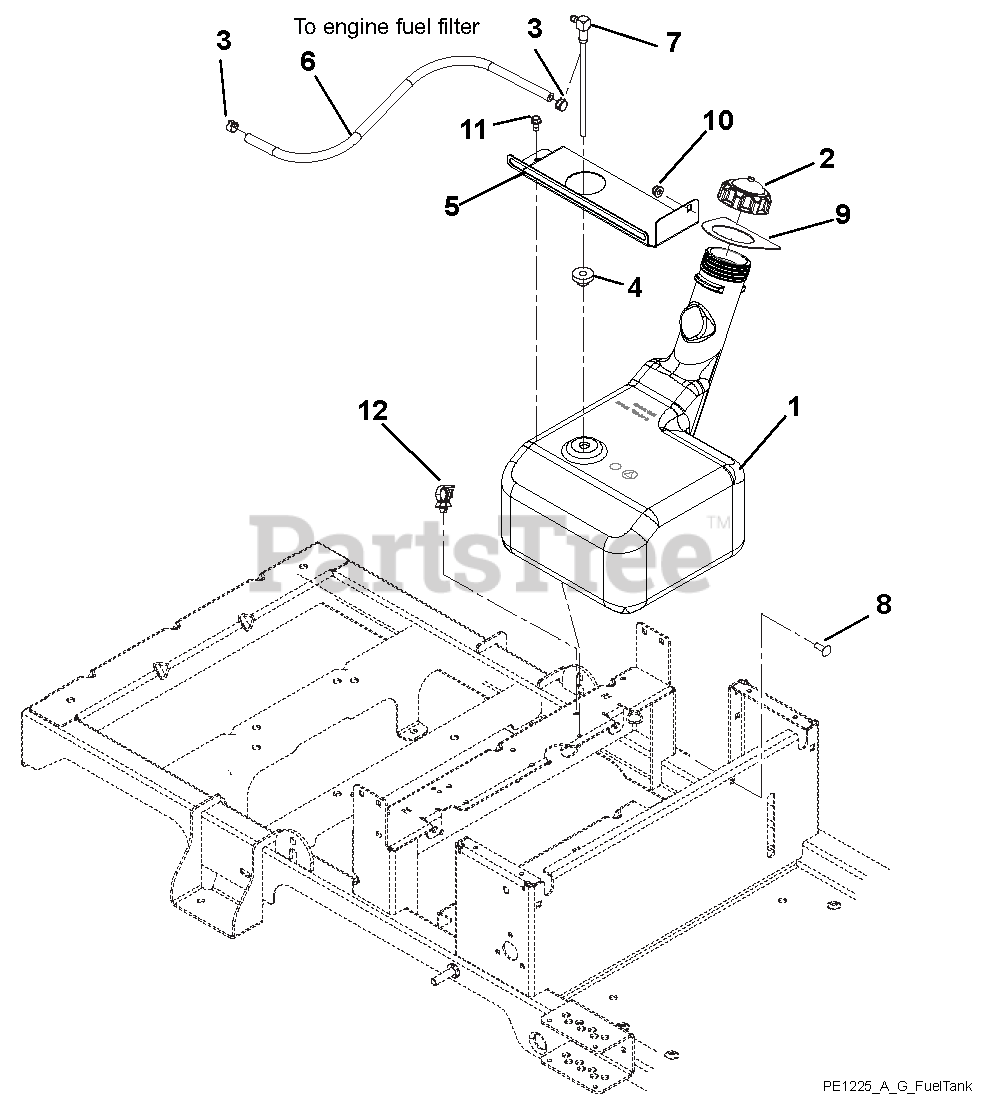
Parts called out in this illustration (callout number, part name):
1	FUEL TANK
2	FUEL CAP
3	CLAMP, FUEL LINE
4	BSHG-FLG .375X1.062X.625 NITR
5	BRKT, TANK STRAP
6	HOSE, .25 LOW-PERM BULK GAS
7	FUEL PICK UP TUBE
8	@BLT-RDHDSQNK .25-20X.75 G5YZ
9	SEAL-TANK NECK
10	@NUT-LK-NYL-FLG .25-20 YWZC
11	SCR-TAP .25-20X.50 HWH TR YWZ
12	WIRE CLIP
